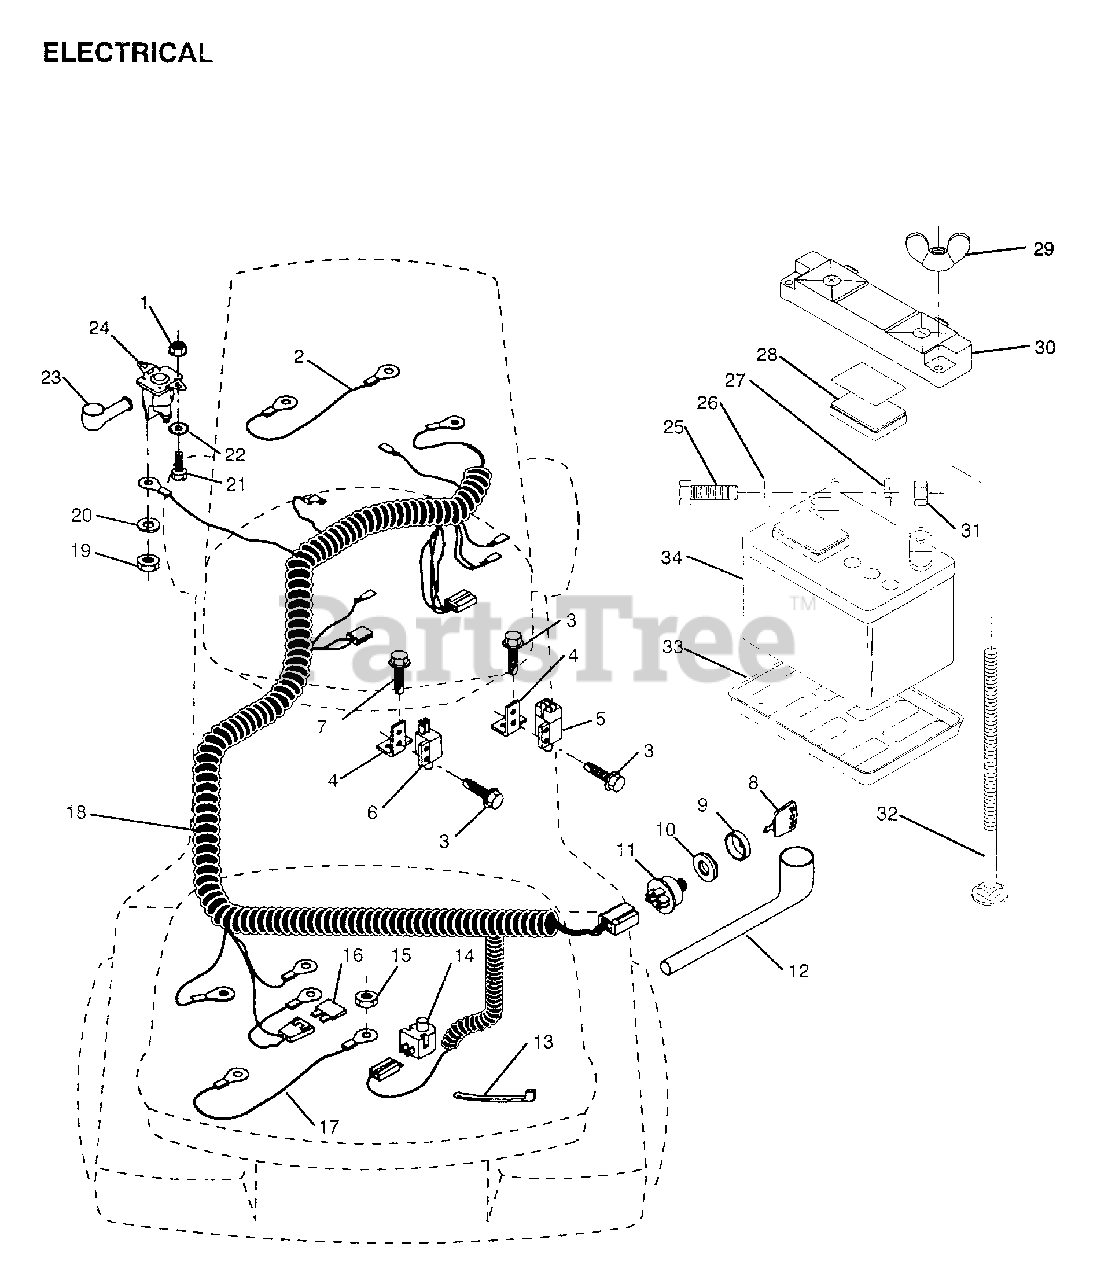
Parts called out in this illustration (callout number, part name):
1	NUT
2	CABLE LTV
3	SCREW
4	BRACKET LT
5	SWITCH INTERLOCKT
6	SWITCH-INTER. GT
7	SCREW
8	KEY
10	NUT IGNITION
12	COVER IGNITION SW
13	WIRE TIE
14	SWITCH SEAT
16	FUSE HYT
18	HARNESS IGNITION
19	NUT
21	BOLT
25	BOLT LT
26	WASHER
27	LOCKWASHER
32	BOLT
33	"TRAY T, BATTERY"
